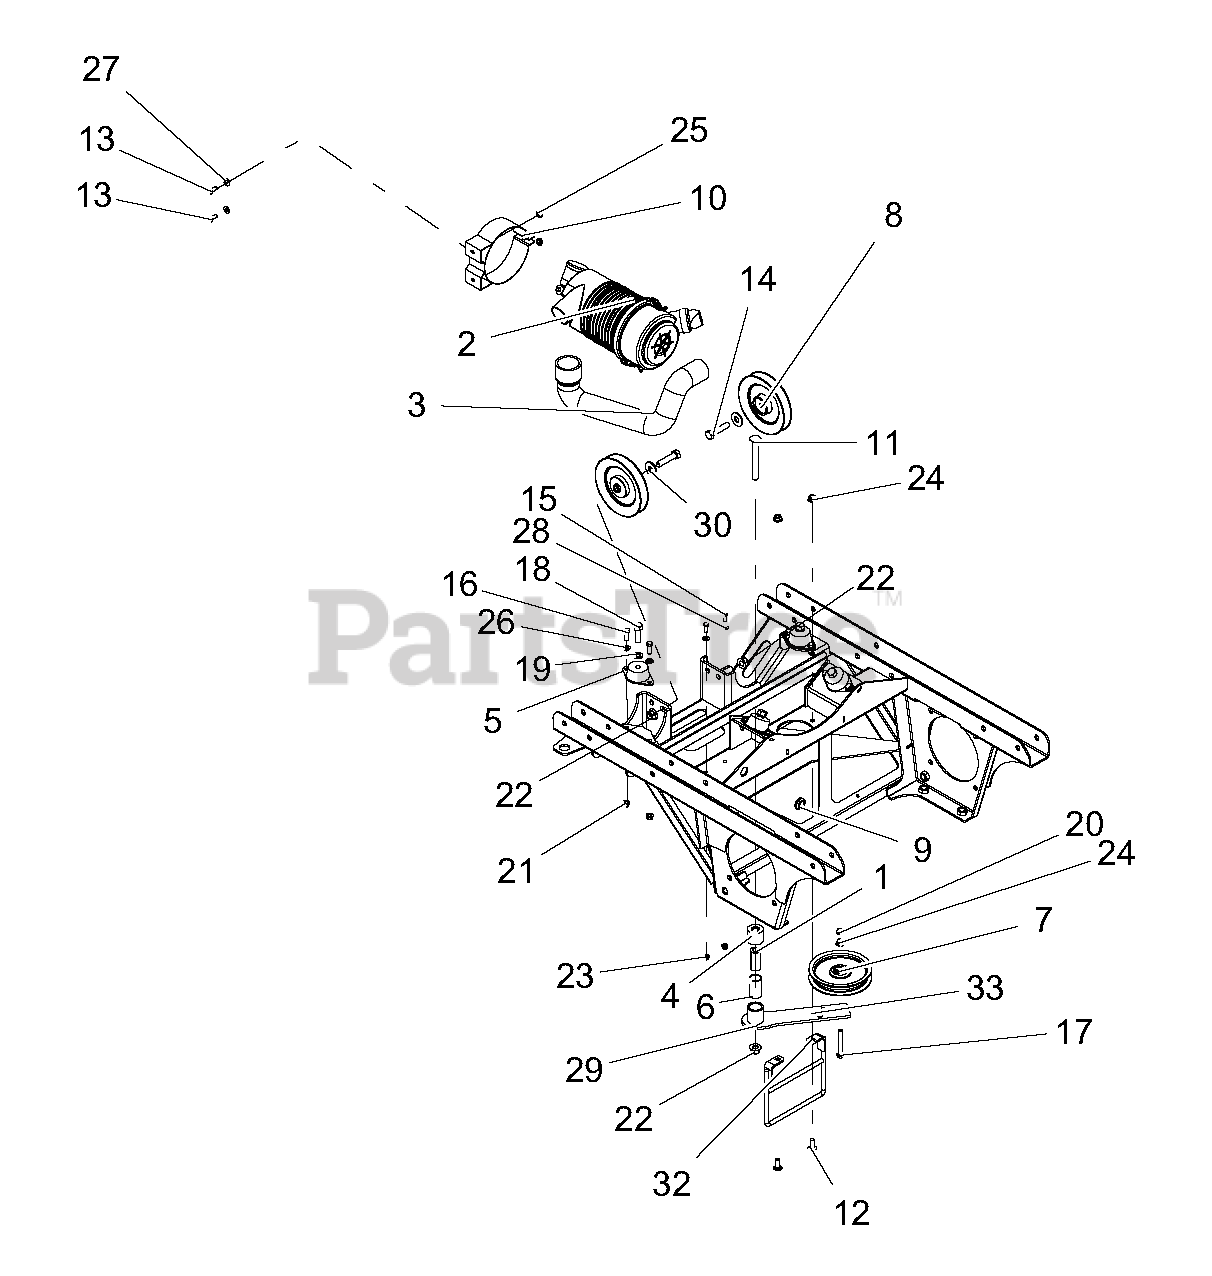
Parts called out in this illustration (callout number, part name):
1	BSHG, SPCR .502X.997X2.03
2	AIR, CLEANER
3	HOSE, FORMED AIR CLEANER OUTLET
4	SPCR, PT400 DIESEL IDLER ARM
5	MOUNT, ENGINE. VIBRATION ISO
6	BSHG, 1.00X1.125X1.937
7	IDLER, FLAT 5.00 X 3.8
8	PULLEY, V-IDLER 6.0X.500 ID DBL BRG
9	GROMMET, RUBBER
10	BRKT, AIR CLEANER MOUNT
11	@BLT-RDHDSQNK .50-13X4.50 G5 YWZC
12	@BLT-RDHDSHSQNK.38-16X1.0 G5YZ
13	BLT-HEX .31-18X.75 GR5 YWZC
14	BLT-HEX .50-13X2.25 GR5 YWZC
15	BLT-HEX .25-20X.75 GR5 YWZC
16	BLT-HEX .31-18X1.00 GR5 YWZC
17	BLT-HEX .38-16X2.75 GR5 YWZC
18	BLT-HEX .50-20X1.50 GR5 YWZC
19	@WSHR-LK .50X.125 REG YWZC
20	@NUT-LK-CTR .38-16 YWZC
21	NUT-LK-NYL-FLG .31-18 YWZC
22	NUT-LK-NYL-FLG .50-13 YWZC
23	NUT-LK-NYL-FLG .25-20 YWZC
24	NUT-LK-NYL-FLG .38-16 YWZC
25	@NUT-SPNLK-FLG .312-18 YWZC
26	@WSHR-FL-STL.344X.688X.065YWZC
27	@WSHR-FL-STL.406X.812X.065 YWZ
28	@WSHR-FL-STL.281X.62X.065 YWZC
29	@WSHR-FL-STL.531X1.06X.095YWZC
30	@WSHR-FL-STL.563X1.38X.109YWZC
32	WLDMT, DIESEL BELT FINGER
33	WMT, IDLER ARM GROUND
